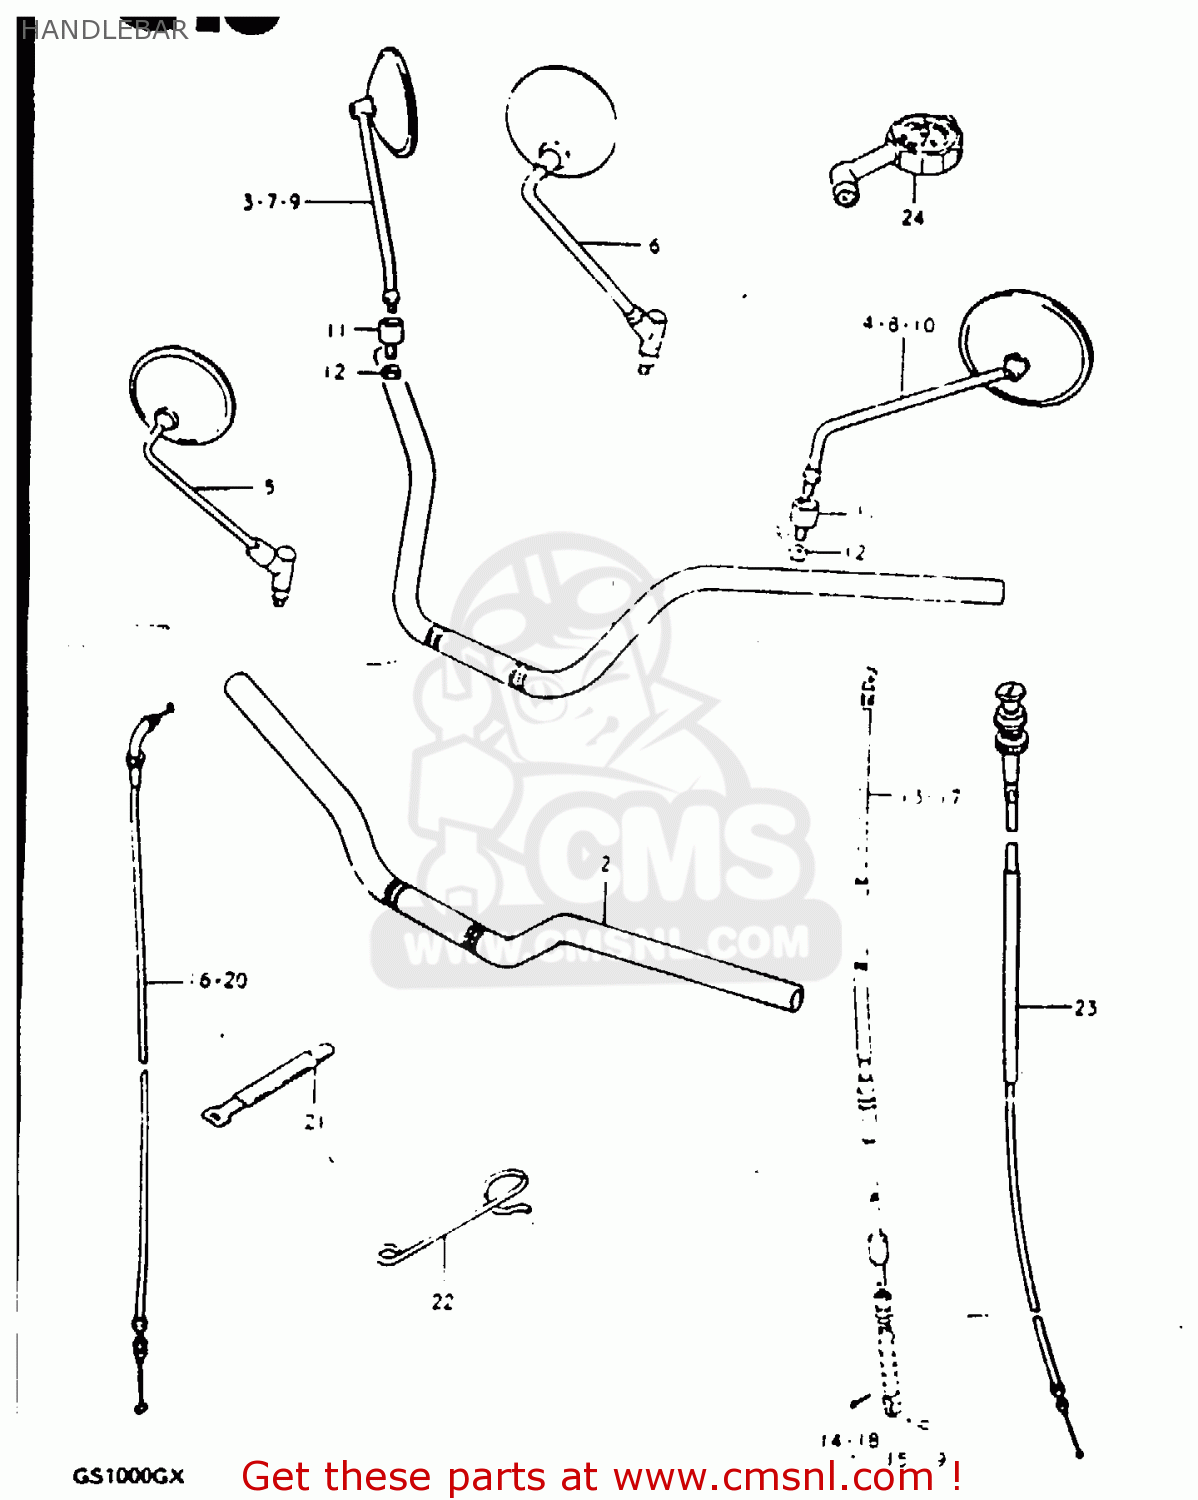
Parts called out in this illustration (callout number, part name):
1	HANDLEBAR
2	HANDLEBAR
3	MIRROR ASSEMBLY,RIGHT
4	MIRROR ASSEMBLY,LEFT
5	MIRROR ASSY,RH
11	CUSHION,REAR VIEW MIRROR
12	NUT
13	CABLE ASSEMBLY,CLUTCH
14	PIN(L:15)
15	PIN
16	CABLE ASSEMBLY,THROTTLE
17	CABLE ASSEMBLY,CLUTCH
18	PIN(L:15)
19	PIN
20	CABLE ASSEMBLY,THROTTLE
21	CLAMP
22	GUIDE,CLUTCH CABLE
23	CABLE ASSEMBLY,STARTER
24	GAUGE ASSY,AIR PRESSURE
